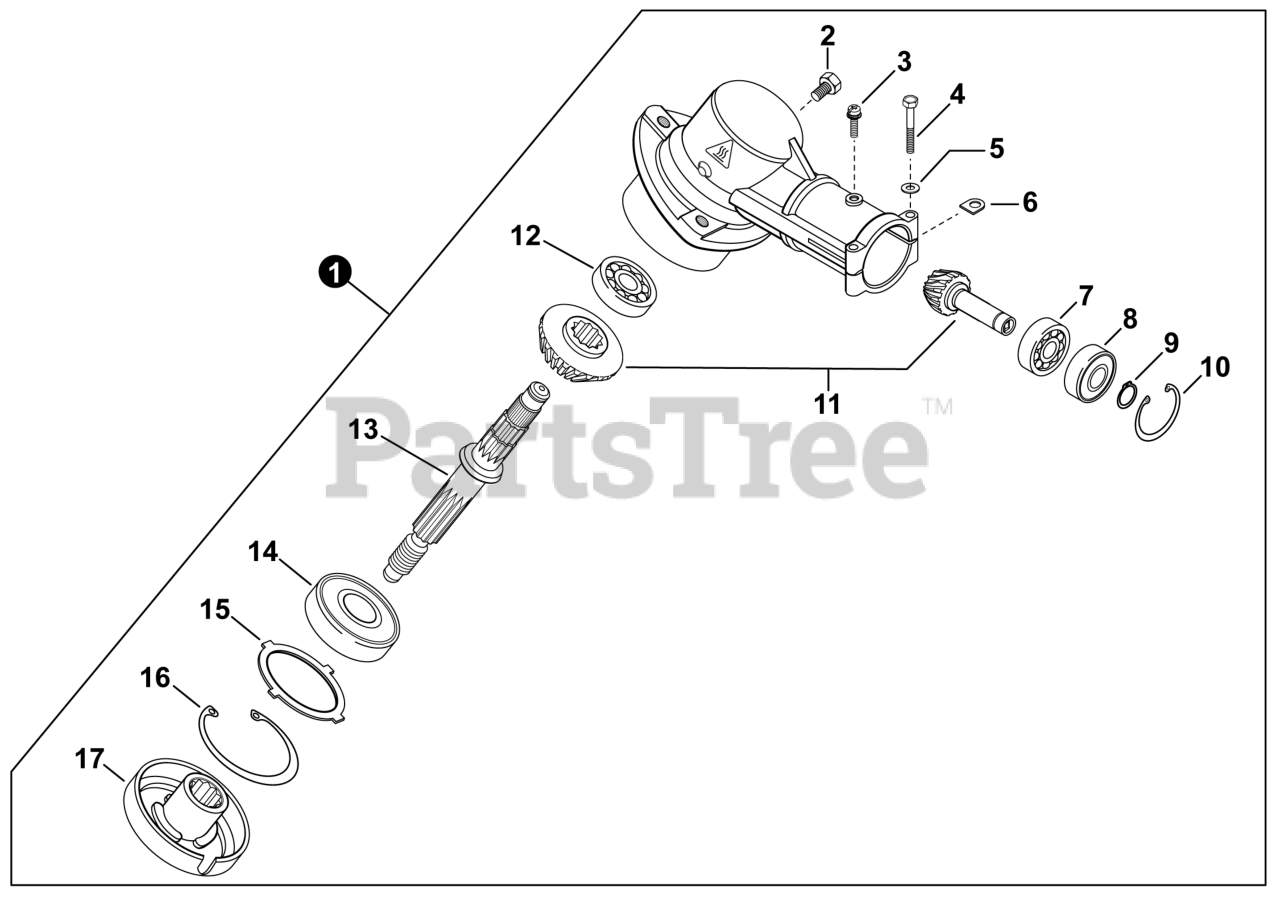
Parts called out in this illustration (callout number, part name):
1	GEAR CASE ASSY
2	BOLT M8x8
3	SCREW 5x10
4	BOLT HSH CB-5x35
5	WASHER, FLAT 5.5x10x0.8
6	D-WASHER
7	BEARING, BALL 6900
8	BEARING, BALL 6900Z
9	RING, SNAP 10
10	RING, SNAP 22
11	GEAR SET
12	BEARING, BALL 609
13	SHAFT, GEAR
14	BEARING, BALL 6201
16	RING, SNAP 32
17	PLATE, ADAPTOR - UPPER
